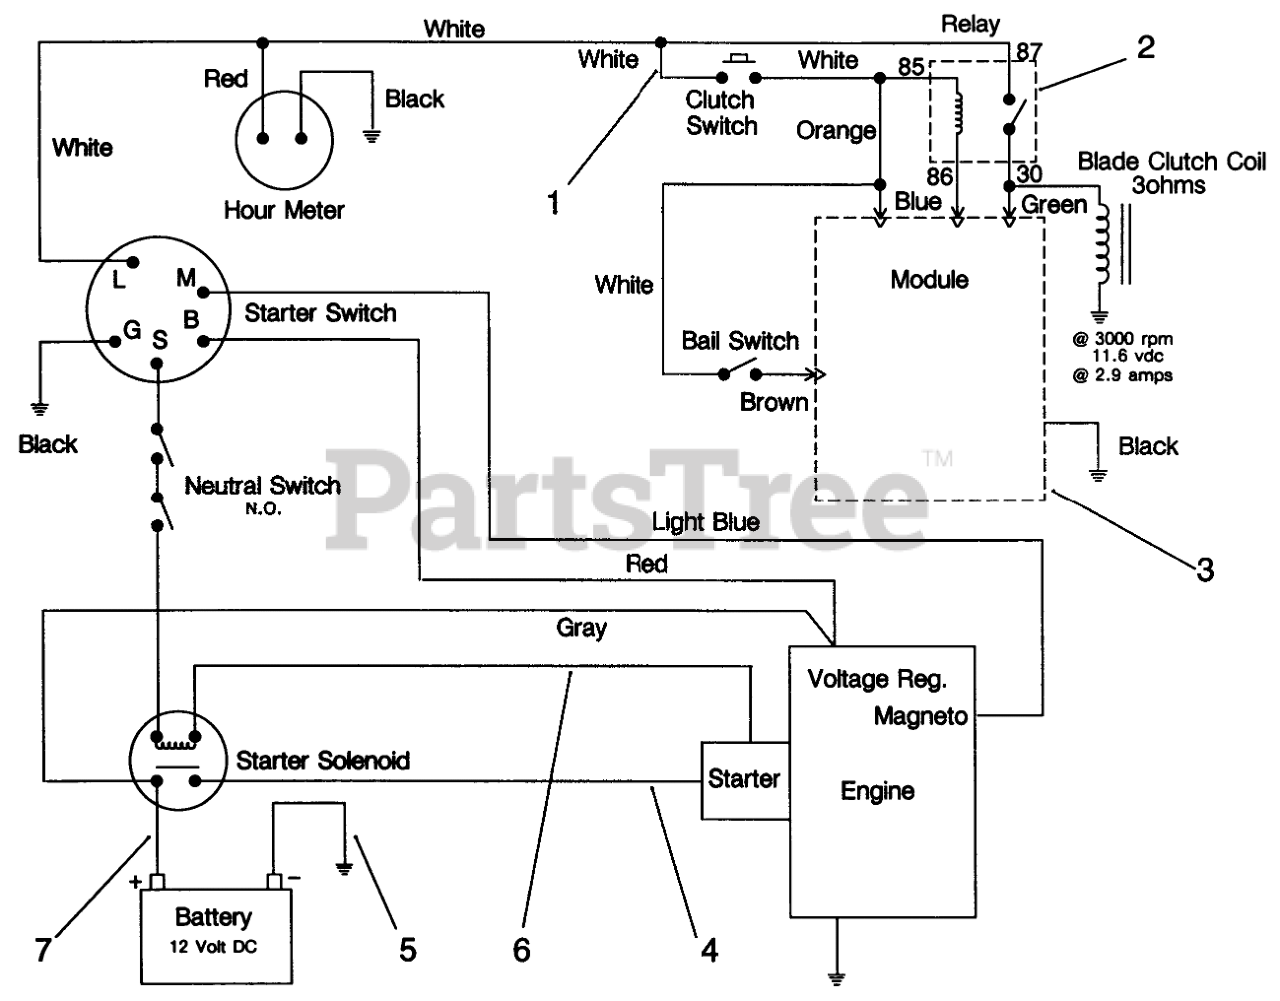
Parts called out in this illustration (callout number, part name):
1	WIRE HARNESS
2	Relay
3	Module
4	WIRE-SOLENOID/STARTER
5	CABLE-BATTERY, NEGATIVE
6	WIRE ASM
7	WIRE ASM
